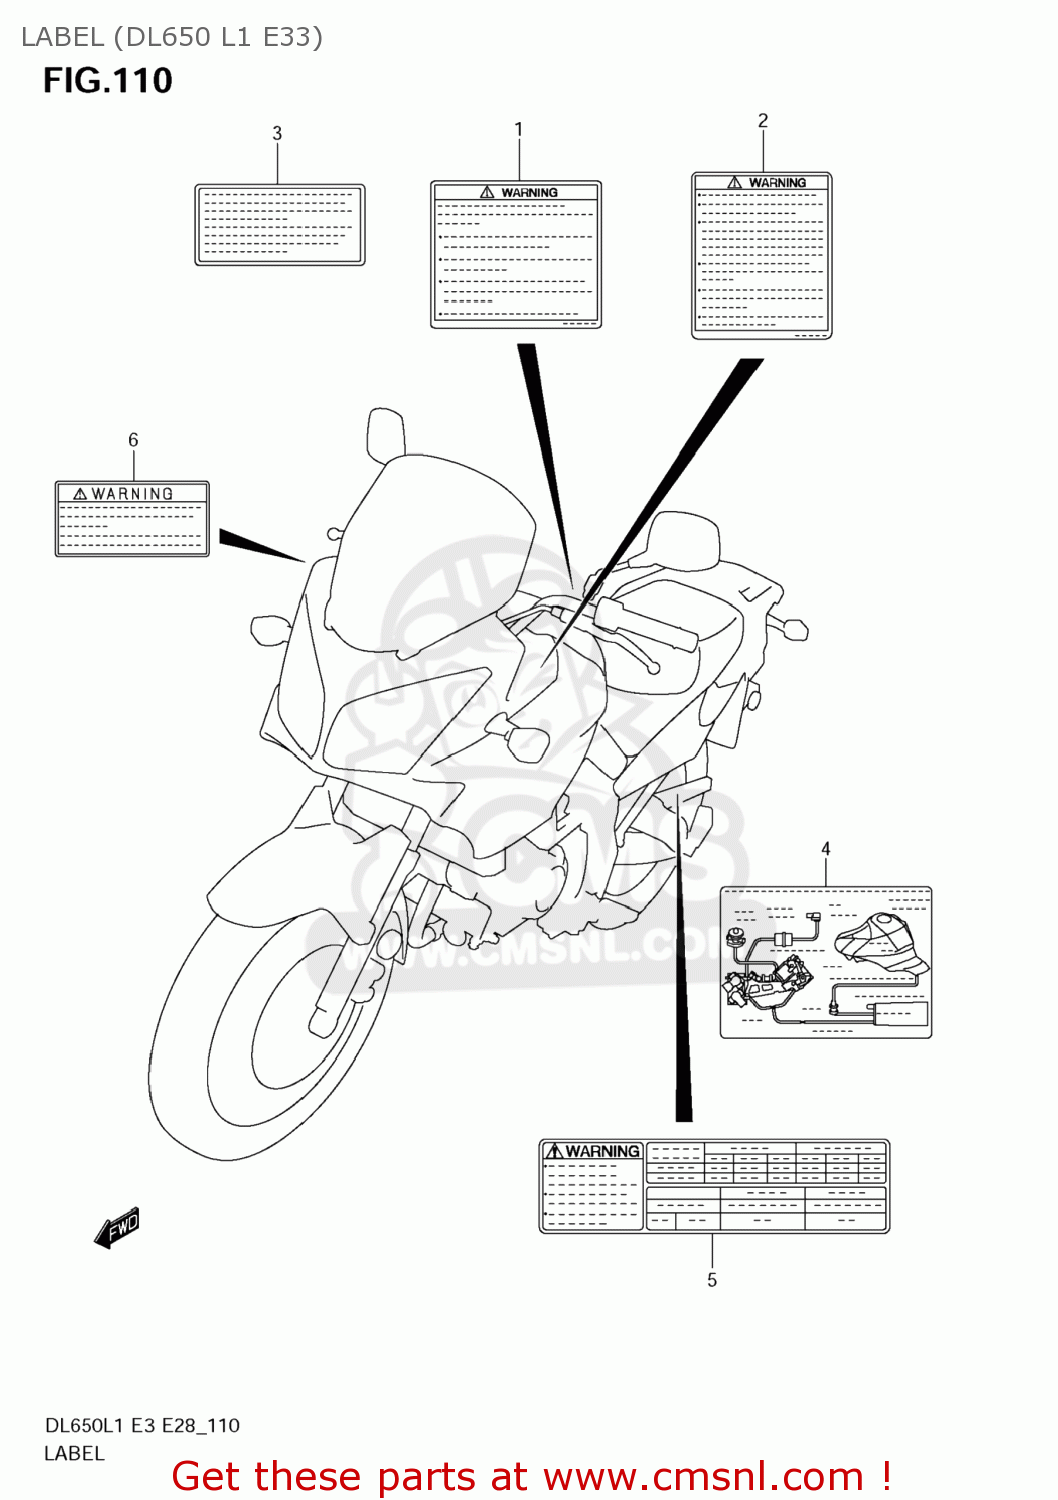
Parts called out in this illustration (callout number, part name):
1	LABEL,GENERAL WARNING
2	LABEL,SCREEN
3	LABEL,MANUAL NOTICE
4	LABEL,HOSE ROUTING
5	LABEL,TIRE INFORMATION
6	LABEL,WARNING STEERING
7	MANUAL,OWNER'S
